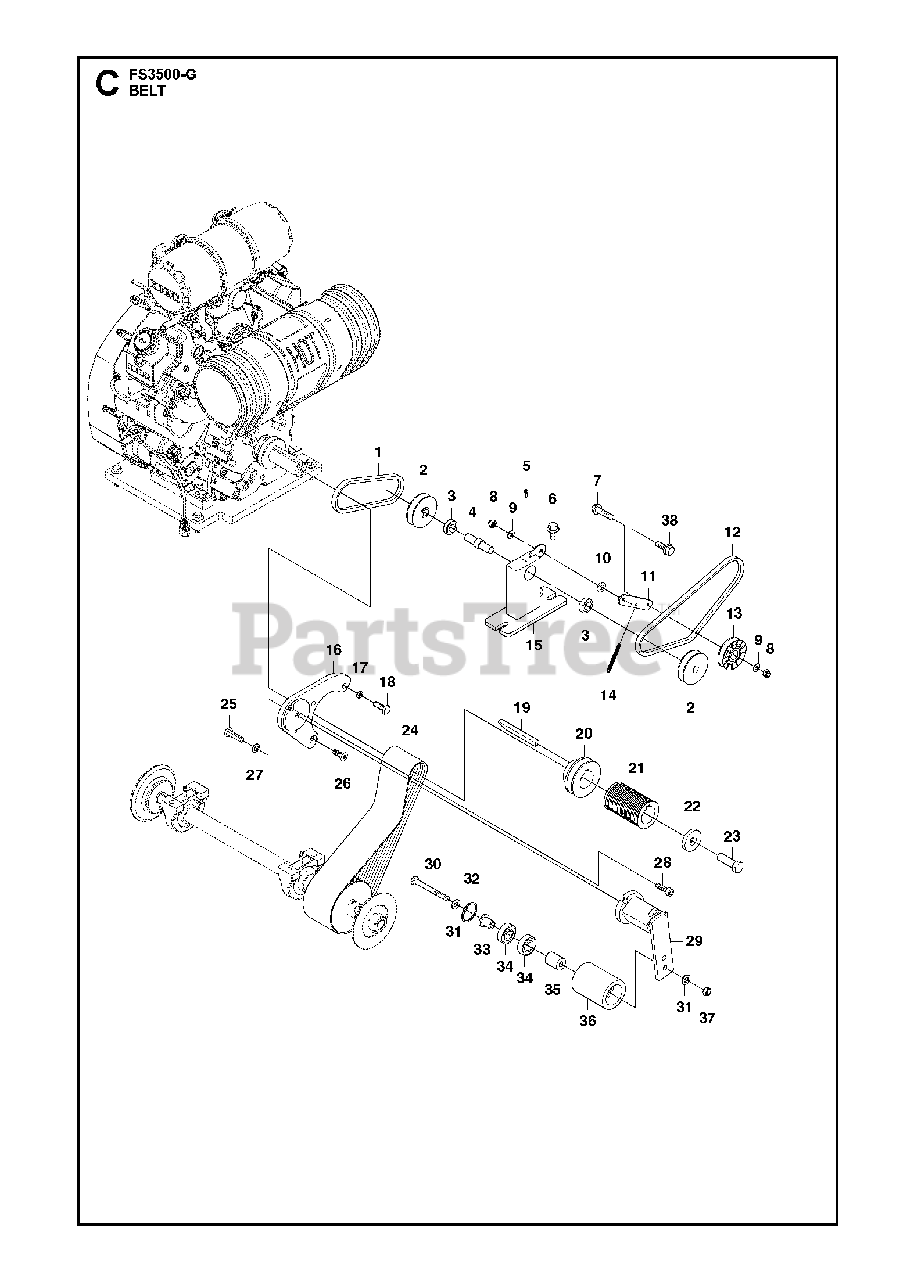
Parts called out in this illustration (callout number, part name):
8	HEXAGON LOCKING NUT
9	WASHER
10	WASHER
17	WASHER
31	WASHER
